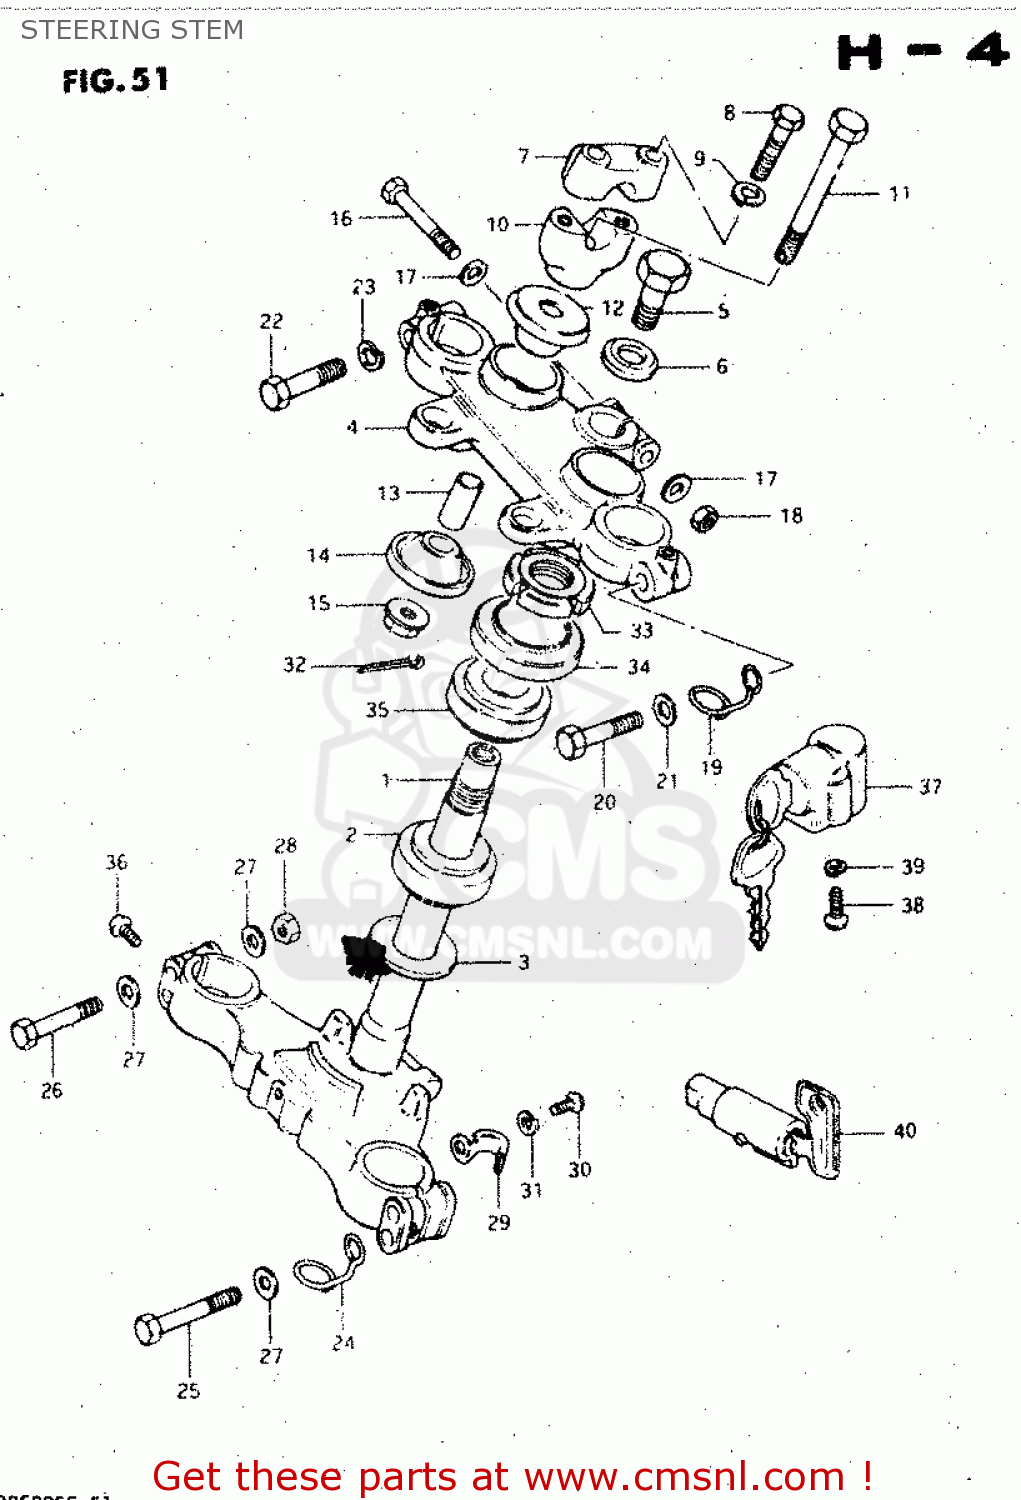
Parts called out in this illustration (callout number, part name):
1	STEM,STEERING
2	BEARING
3	WASHER,THRUST
4	STEM HEAD, STEERING
5	BOLT,STEERING STEM HEAD
6	WASHER
7	HOLDER, HANDLE UPPER
8	BOLT
9	LOCK WASHER
10	HOLDER,HANDLEBAR
11	BOLT,HANDLE HOLDER
12	CUSHION,HANDLE,UPPER
13	SPACER(10.2X14X46)
14	CUSHION,HANDLE,LOWER
15	NUT
16	BOLT 8X55
17	WASHER
18	NUT
19	CLIP
20	BOLT 10X40
21	WASHER
22	BOLT,FORK INNER TUBE F
23	LOCK WASHER
24	GUIDE,CABLE
25	BOLT
26	BOLT 8X55
27	WASHER
28	NUT
29	CLIP,BRAKE CABLE
30	SCREW
31	LOCK WASHER
32	PIN 20X20
33	NUT,STEERING STEM(25X44X10)
34	DUST SEAL,STEERING,UPPER
35	TAPER,ROLLER BEARING
36	SCREW 5X6
37	LOCK ASSY,STEERING
38	SCREW
39	LOCK WASHER
40	LOCK ASSY,STEERING(NEIMAN)
